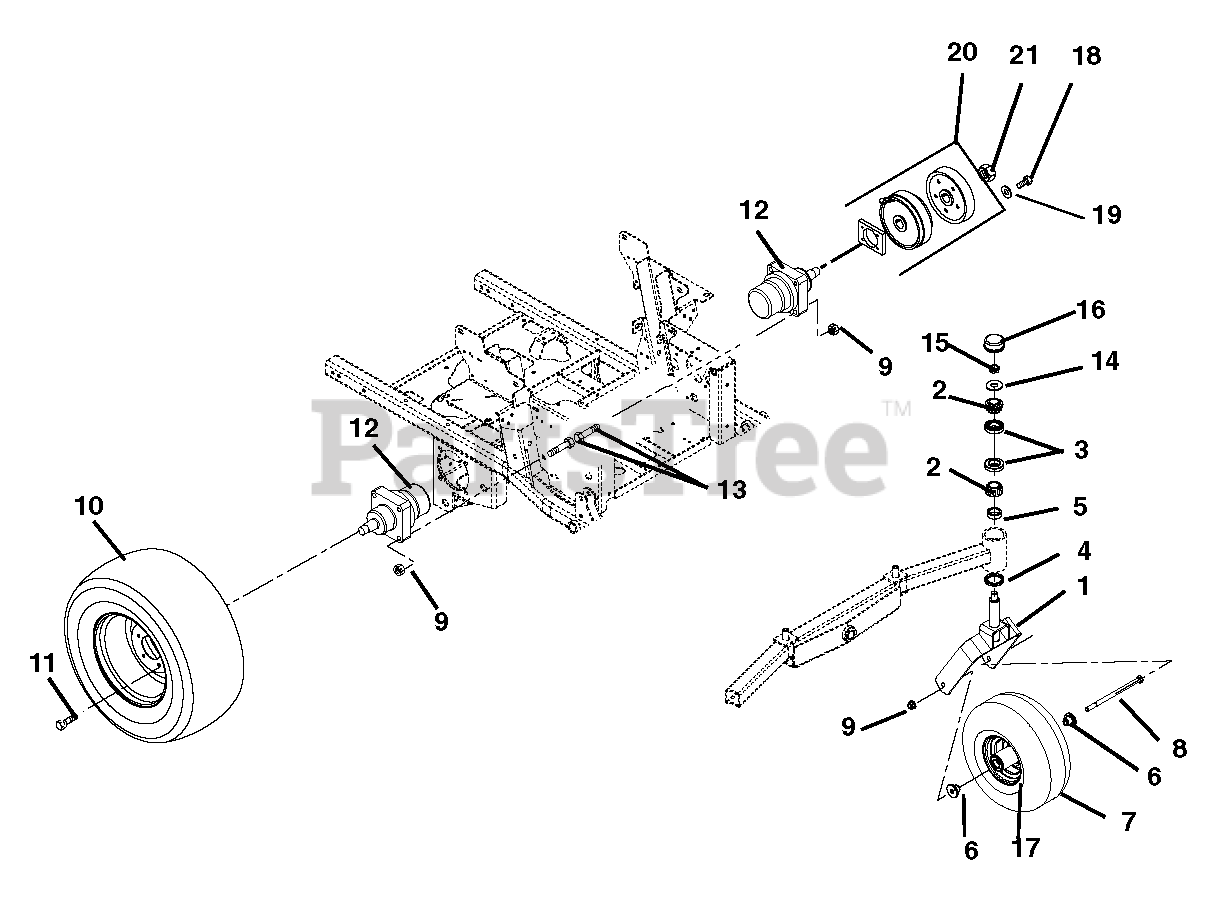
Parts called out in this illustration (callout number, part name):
1	Fork, Front
2	Bearing, Cone
3	Bearing, Cup 2.328 x .465
4	Bearing Seal 1.75 x 2.332 x .312
5	Spacer, 1.258ID x 1.750OD x .550
6	Spacer, Wheel
7	Wheel/Tire Assembly
8	Bolt, Hex .50-13 x 9.00 Grade 5
9	Nut-Locking-Top-Flange .50-13
10	Tire/Wheel Assembly, 24 x 11.50-12
11	Bolt, Lug .50-20 x 1.38
12	Wheel Motor, 18E (CCW)
13	Bolt, Wheel Motor .50-13 x 2.75 Grade 8
14	Washer, Flat Steel, .812 x 1.50 x .135
15	Nut, Locking-Jam-Patch 1.00-20
16	Cap, Dust
17	Bearing, 25mm I.D. x 52mm OD x 15mm
18	Bolt, Hex .31-18 x 1.50 Grade 8 EP30
19	Waher, Lock .31 x .078
20	Kit, Parking Brake Service
21	Nut, Locking Jam Patch 1.00-20
